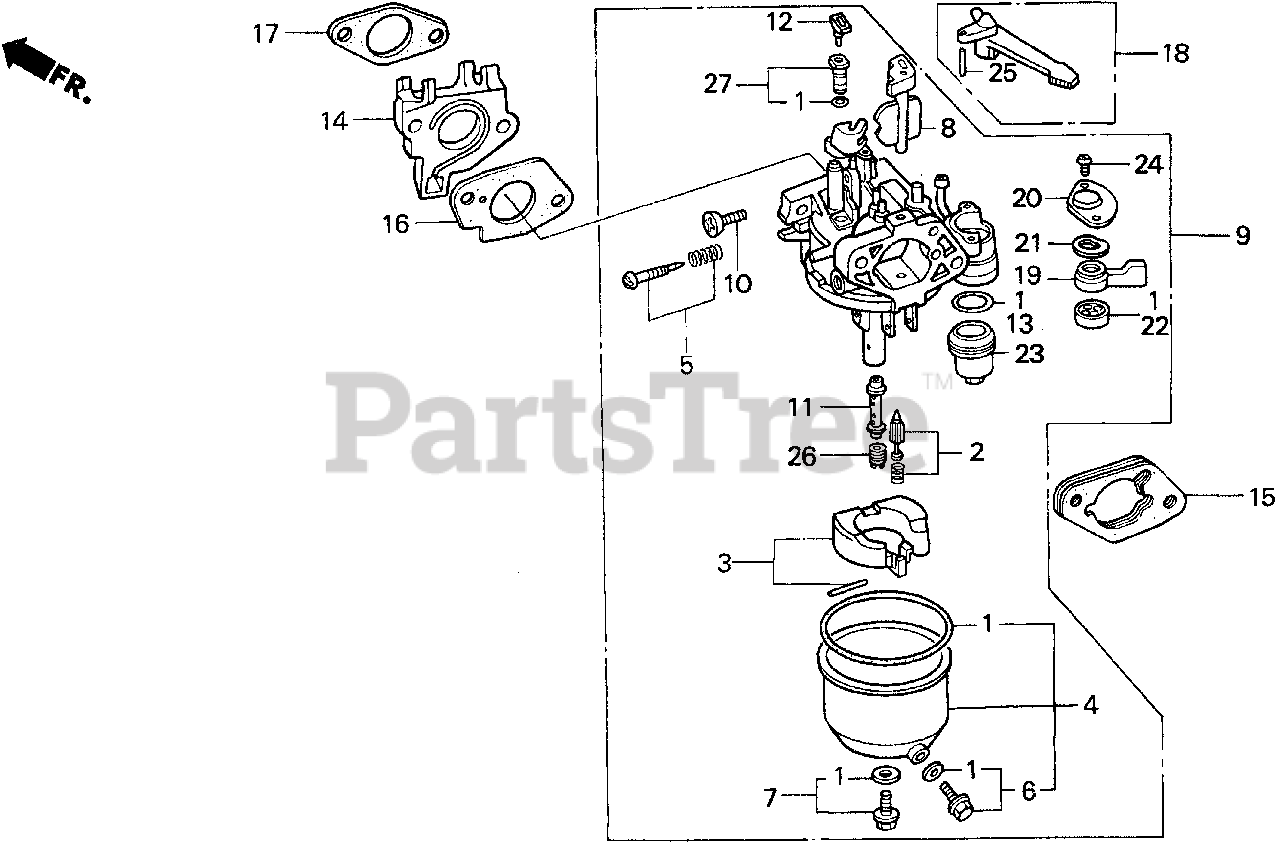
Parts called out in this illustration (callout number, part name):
1	GASKET SET
2	VALVE SET, FLOAT
4	CHAMBER SET, FLOAT
5	SCREW SET
6	SCREW SET, DRAIN
7	SCREW SET B
9	CARBURETOR ASSY. (BE80D B)
10	SCREW, THROTTLE STOP
11	NOZZLE, MAIN
12	COLLAR, SET
13	GASKET, FUEL STRAINER CUP
14	INSULATOR, CARBURETOR
15	SPACER, CARBURETOR
16	GASKET, CARBURETOR
17	GASKET, INSULATOR
18	LEVER, CHOKE (STD)
19	LEVER, VALVE
20	PLATE, LEVER SETTING
21	SPRING, VALVE LEVER
22	GASKET, VALVE
23	CUP, FUEL STRAINER
24	SCREW, PAN (3X6)
25	PIN, SPRING (2X12)
26	JET, MAIN (#90)
26	JET, MAIN (#92)
26	JET, MAIN (#95)
27	JET SET, PILOT (#35)
